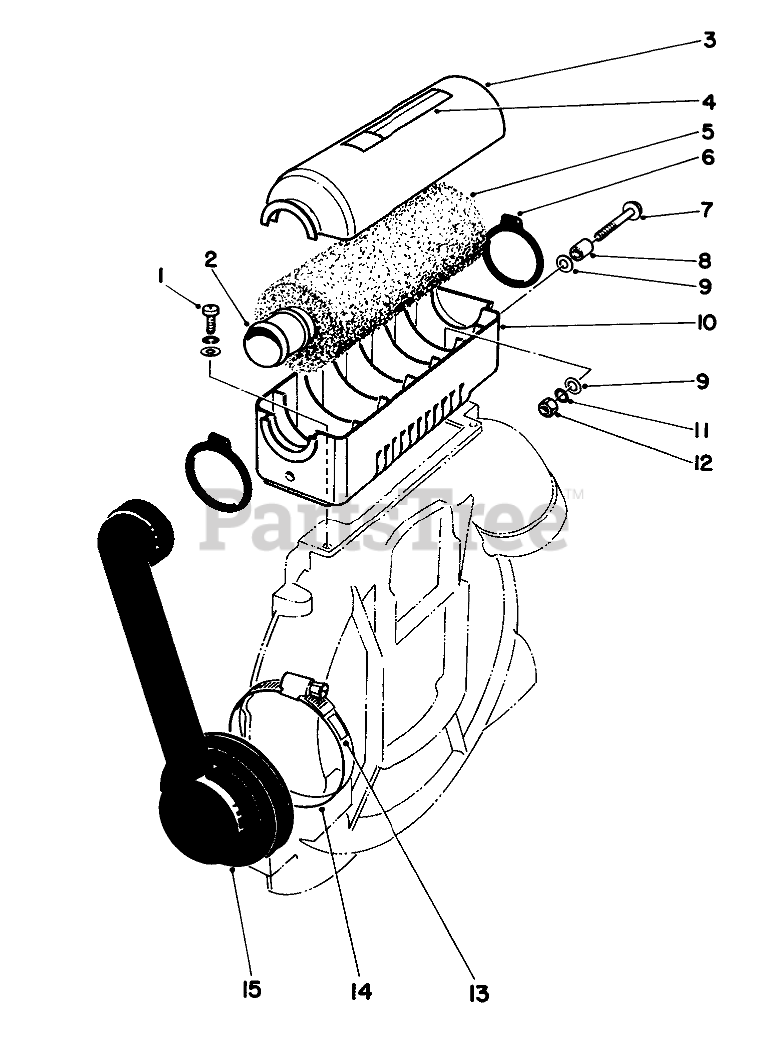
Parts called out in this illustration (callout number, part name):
1	Screw
2	AIR FILTER HOLDER
3	Case-Upper
4	Decal-Warning
5	AIR FILTER
6	CLAMP
8	Spacer
9	WASHER
10	Case-Lower
11	Lockwasher
13	Decal-Choke
14	CLAMP
15	Adapter-Intake
